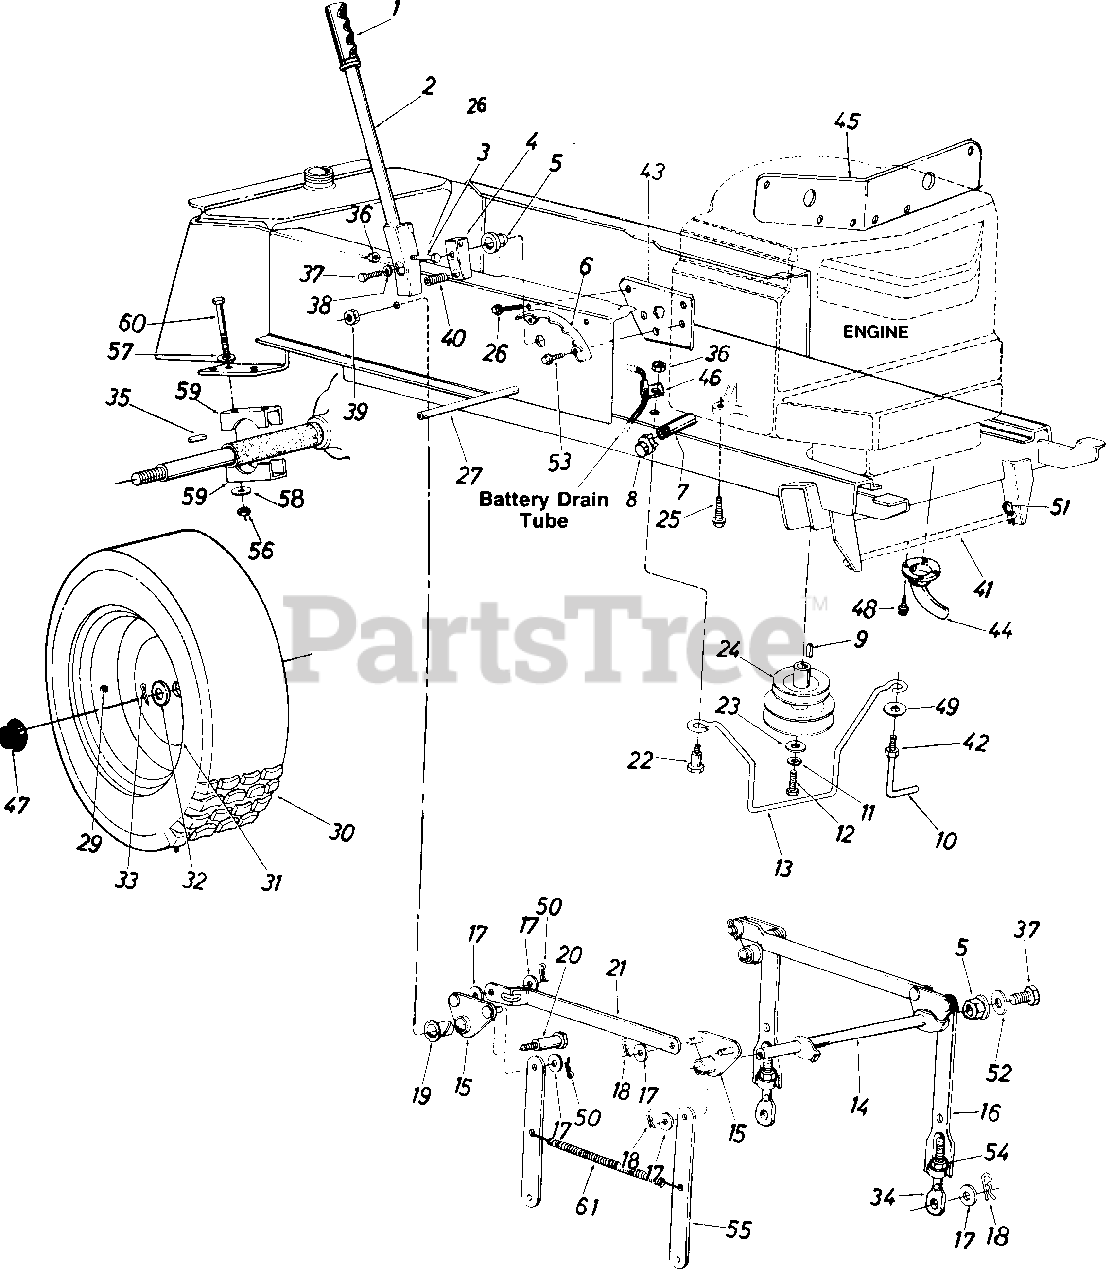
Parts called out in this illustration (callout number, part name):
1	Grip
2	Lift Handle Ass'y.
3	Hex Scr. 5/16-18 x 1.50" Lg.
4	Lift Shaft Drive
5	Plastic Hex Brg. 5/8" I.D.
8	Pipe Cap 3/8-18 Npt.
9	Sq. Key 1/4" x 1/4" x 1.50" Lg.
10	Belt Guard Lock Pin
11	L-Wash. 7/16" Scr.
12	Hex Scr. 7/16-20 x 1.50" Lg.
13	Belt Guard
14	Lift Shaft Ass'y.
15	Lift Pivot Brkt. Ass'y.
16	Adj. Deck Lift Link
17	Fl-Wash. 1/2" I.D. x 1.00" O.D. x .090
18	Hairpin Cotter
19	Nyliner 5/8" I.D. x .88" Lg.
20	Shld. Scr. 5/8" Dia. x .96" Lg. 3/8-16
23	Flat Wash. .44" I.D. x 1.25" O.D. x .17
24	Two-Step Engine Pulley 4.75" & 5.56
25	Hex Wash. Hd. Scr. 3/8-16 x 1.25" Lg.
26	Hex Thd. Rolling Scr. 5/16-24 x.50" Lg.
27	Running Board Rod
29	Air Valve
30	Rear Wheel Ass'y. Comp.
33	Cotter Pin 3/16" Dia. x 1.50" Lg.
34	Eye Bolt Adj. Link 1/2-13 Thd.
35	Sq. Key 1/4 x 3.01
36	Hex Cent. L-Nut 5/16-18 Thd.
37	Hex Scr. 5/16-24 x .62/ Lg.
38	L-Wash. 5/16 Scr.
39	Hex Top L-Nut 3/8-16 Thd.
40	Compression Spring
41	Deck Connecting Rod
42	Hex Nut 5/16-24 Thd.
45	Heat Shield
46	Mounting Clamp
47	Hub Cap
48	Hex Wash. Hd. AB-Tap Scr. #10 x .50 Lg.
49	Belle-Wash. .39" I.D.
50	Cotter Pin .09 Dia. x 1.0" Lg.
51	Int. Cotter Pin
52	Flat Wash. .34" I.D. x 1.12" O.D. x .125
53	Hex Wash. Hd. AB-Tap Scr. 5/16 x .62" Lg.
54	Hex Nut 1/2-13 Thd.
56	Hex Nut 3/8-16 Thd .
57	Fl-Wash. .385" I.D. x .87' O.D.
58	Bell-Wash. .39" I.D. x 1.13" O.D.
59	Rear Axle Bracket
60	Hex Bolt 3/8-16 x 3.5" Lg.
61	Extension Spring 8.25" Lg.
